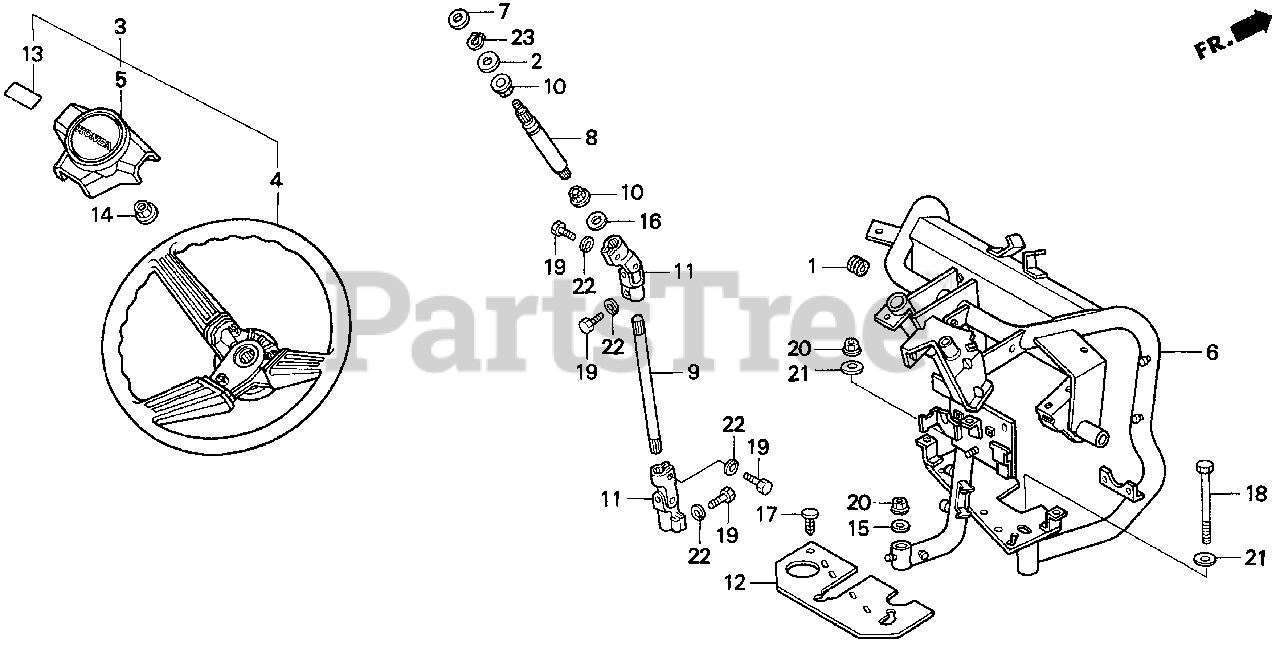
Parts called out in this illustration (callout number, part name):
1	RUBBER, BATTERY BOX SETTING
2	SEAT, FR. RUBBER SPRING
3	WHEEL ASSY., STEERING
4	WHEEL, STEERING
5	PAD, CENTER
6	COLUMN, STEERING
7	WASHER, STEERING COLUMN
8	SHAFT A, STEERING
9	SHAFT B, STEERING
10	BUSH A, STEERING SHAFT
11	JOINT B, STEERING
12	PLATE, COLUMN COVER SEAL
13	MARK, EMBLEM (6H000-4149)
14	NUT, SELF-LOCK
15	WASHER (10.5X27)
16	WASHER (15MM)
17	CLIP, TRIM (5MM) *NH1L* (BLACK)
18	BOLT, HEX. (10X130)
19	BOLT, HEX. (8X28)
20	NUT, FLANGE (10MM)
21	WASHER, PLAIN (10MM)
22	WASHER, SPRING (8MM)
23	CIRCLIP (OUTER) (18MM)
